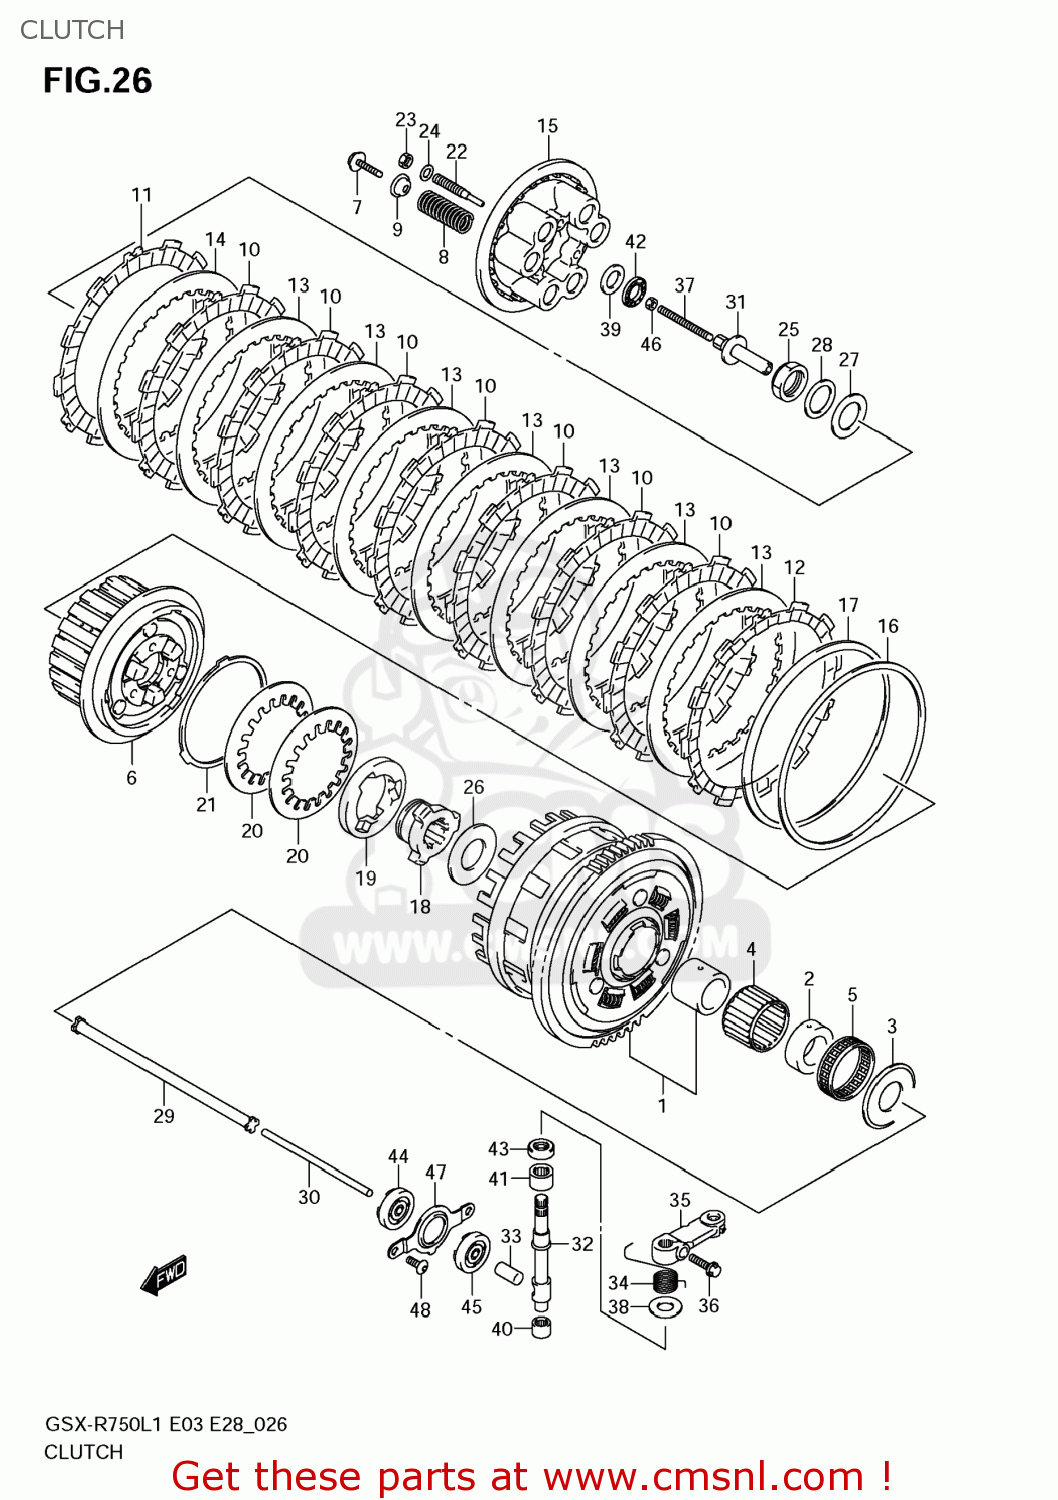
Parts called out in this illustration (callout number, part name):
1	GEAR ASSY,PRI DRIVEN
2	SPACER,OIL PUMP DRIVE SPROCKET
3	WASHER(25X54X2.4)
4	BEARING(35X40X26.8)
5	BEARING(35X40X12)
6	HUB,CLUTCH SLEEVE
7	BOLT,CLUTCH SPRING
8	SPRING,CLUTCH
9	WASHER
10	PLATE,CLUTCH DRIVE (NAS)
11	PLATE,CLUTCH DRIVE NO.1 (NAS)
12	PLATE,CLUTCH DRIVE NO.3 (NAS)
13	PLATE,CLUTCH DRIVEN (NAS)
14	PLATE,CLUTCH DRIVEN (NAS)
15	DISC,CLUTCH PRESSURE
16	SEAT,WAVE WASHER
17	WASHER,CLUTCH PLATE WAVE
18	CAM,CLUTCH DRIVE
19	CAM,CLUTCH DRIVEN
20	WASHER,CAM REACTION WAVE
21	WASHER,CAM REACTION SEAT
22	LIFTER,CLUTCH PRESSURE DISC
23	NUT,CL PRESS DISC LIFTER LOCK
24	SHIM(8.8X14X1)
25	NUT
26	WASHER(25X50X2.5)
27	WASHER
28	WASHER(25X41X2.5)
29	ROD,CLUTCH PUSH,R
30	ROD,CLUTCH PUSH,L
31	PIECE,CLUTCH PUSH
32	CAMSHAFT,CLUTCH RELEASE
33	CAP,CLUTCH PUSH ROD
34	SPRING,CLUTCH RELEASE RETURN
35	ARM,CLUTCH REL
36	BOLT(6X20)
37	SCREW(6X73)
38	WASHER(10.5X24X1)
39	WASHER(15.5X28X1)
40	BEARING(10X14X10)
41	BEARING(12X18X12)
42	BEARING(15X28X2)
43	SEAL,OIL(10X20X6)
44	SEAL,OIL(6X34X10.5)
45	SEAL,OIL(10X17X5)
46	NUT
47	RETAINER,CL PUSH ROD OIL SEAL
48	SCREW(6X13)
